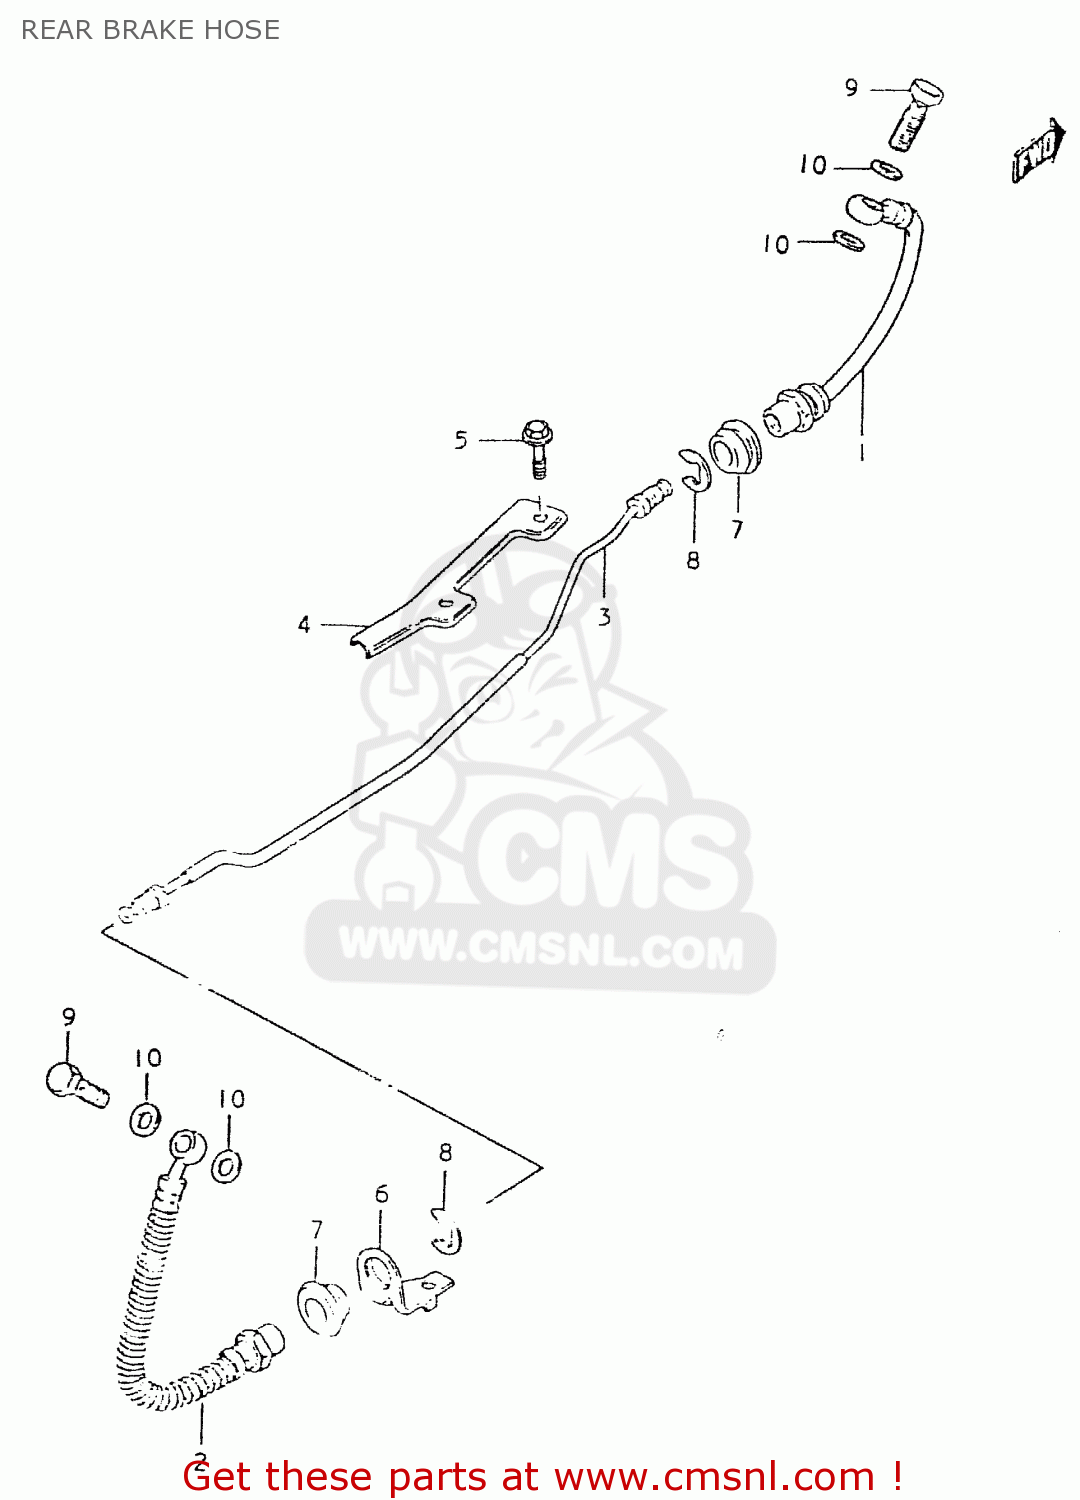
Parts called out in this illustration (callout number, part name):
1	HOSE,REAR BRAKE NO.1
2	HOSE,RR BRAKE NO.2
3	PIPE,REAR BRAKE
4	COVER,REAR BRAKE PIPE
5	BOLT
6	GUIDE,BRAKE HOSE
7	GROMMET,BRAKE HOSE GUIDE
8	E RING
9	BOLT,UNION
10	WASHER
